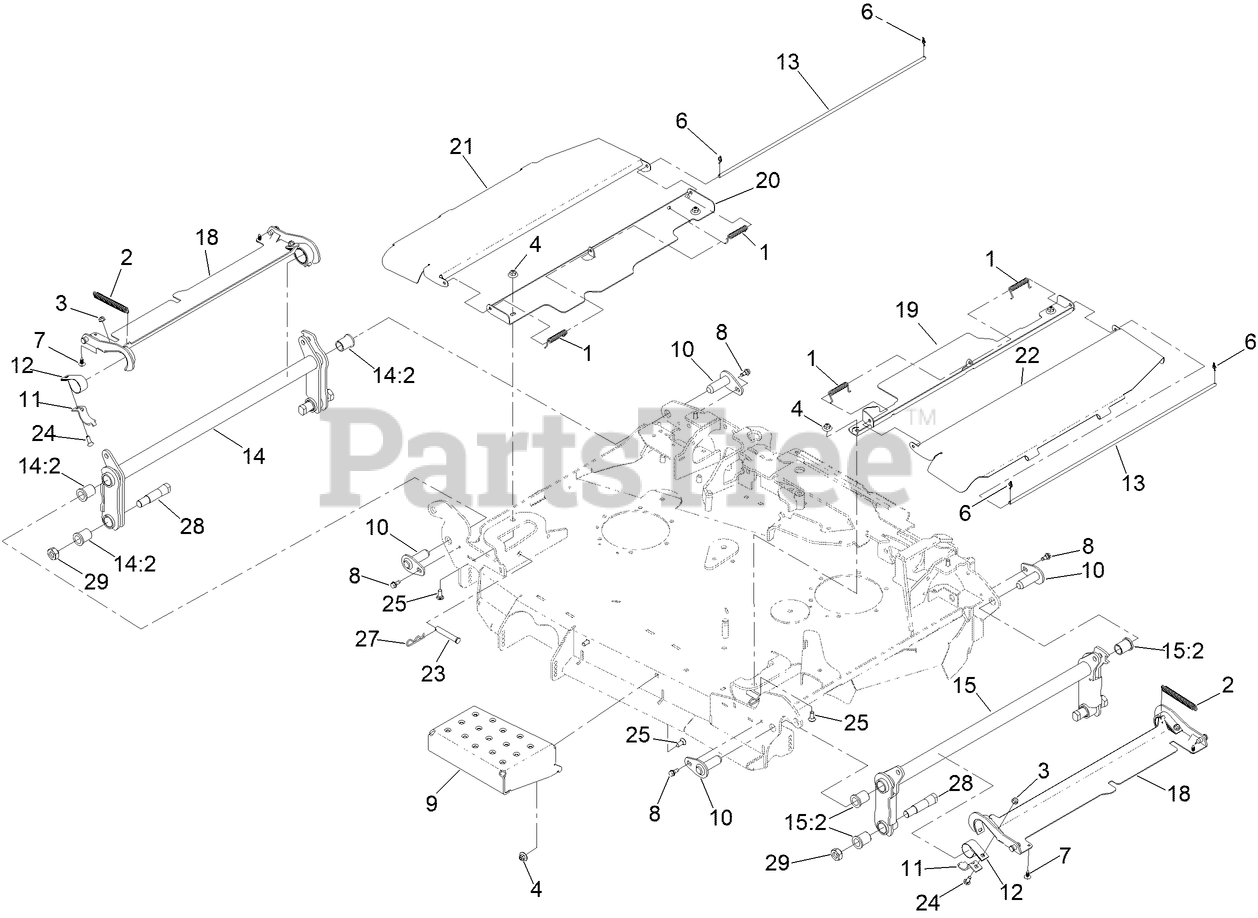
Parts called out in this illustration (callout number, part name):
1	SPRING-TORSION
2	SPRING
3	NUT-HF, NI
4	NUT-FLANGE, NI
6	PIN-COTTER, LOCKING
7	PLUG-PLASTIC
8	SCREW-SHOULDER
9	PANEL-STEP
10	ASM-DECK PIN
11	PLATE-RETAINER, BEARING
12	BEARING-STRAP, NYLON
13	COVER-ROD, PIVOT
14	ASM-FOLS ARM, RH
14:2	BUSHING-FLANGED
15	ASM-FOLD ARM, LH
15:2	BUSHING-FLANGED
18	COVER-WING
19	SHIELD-CENTER, LH
20	SHIELD-CENTER, RH
21	PANEL-SHIELD HINGE, RH
22	PANEL-SHIELD HINGE, LH
23	PIN-CLEVIS
24	SCREW-CARR
25	BOLT-CARR
27	PIN-HAIR
28	BOLT-PIVOT PIN
29	NUT-LUG
